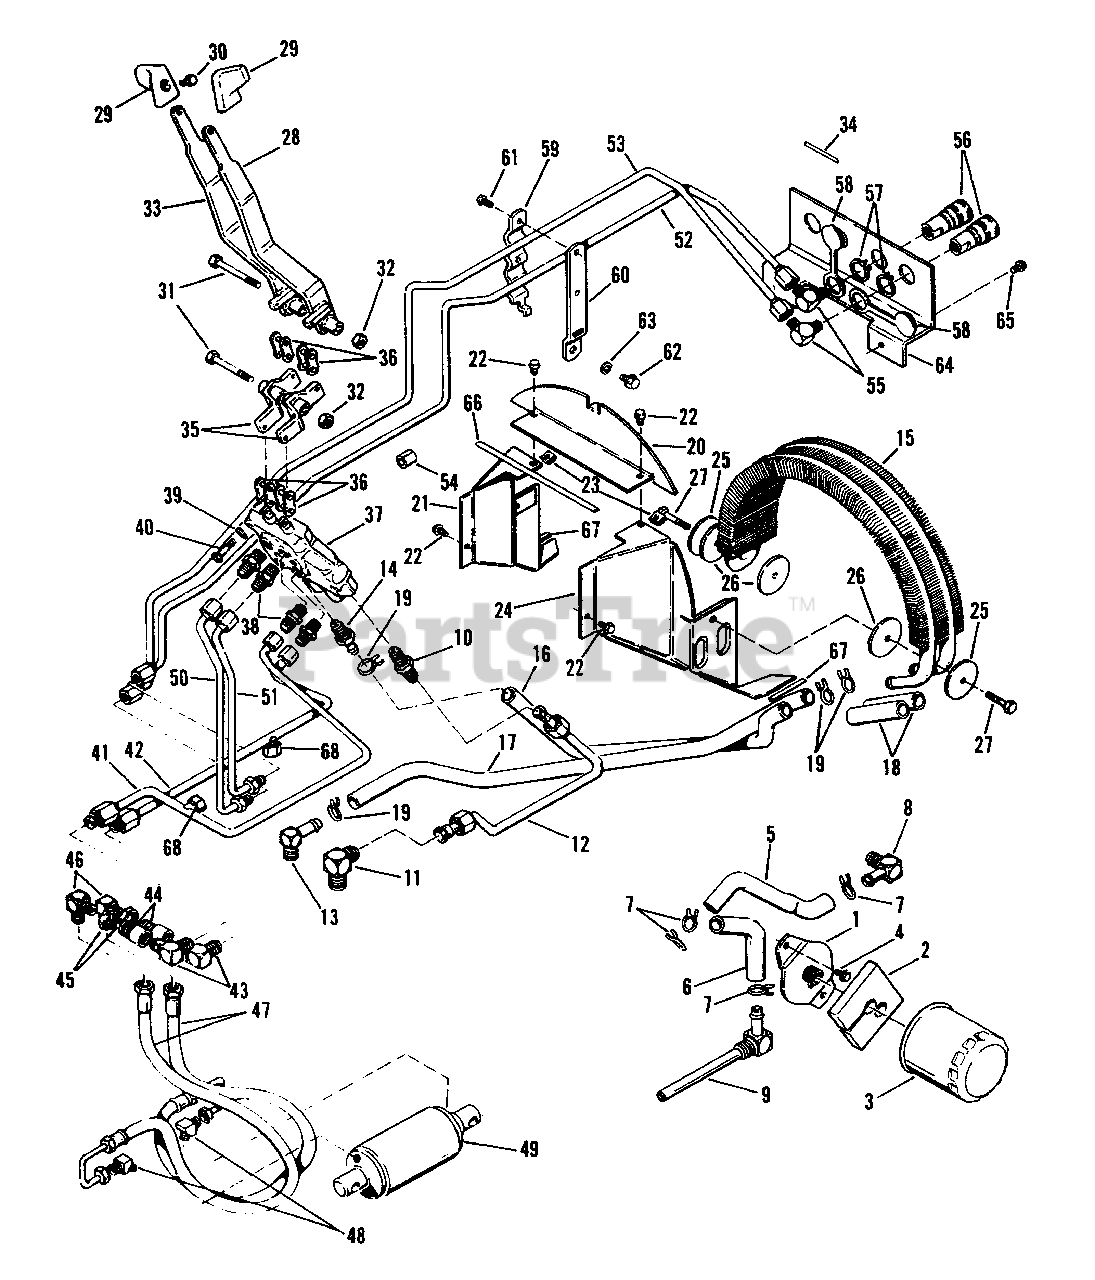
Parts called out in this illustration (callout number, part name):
1	Filter Plate Assembly
3	Oil Filter
4	Hex Capscrew, 5/16"-18 x 1/2" lg.
5	Hydraulic Hose
6	Hydraulic Hose
7	Hose Clamp
8	Elbow Assembly
10	Male Connector
12	Tube Assembly
14	Hose Connector
15	Oil Cooler
16	Hydraulic Hose
17	Hydraulic Hose
18	Hydraulic Hose
19	Hose Clamp
20	Upper Shroud (Rear)
21	Shroud Assembly, Left Hand
22	Thread Forming Screw, 1/4"-20 x 3/8" lg.
23	Speed Nut
24	Shroud Assembly, Right Hand
27	Thread Forming Screw, 1/4"-20 x 1-1/2" lg.
28	Lever Assembly
30	Thread Forming Screw, 1/4"-20 x 3/4" lg.
31	Hex Capscrew, 3/8"-16 x 2-3/4" lg.
32	Hex Jam Nut, 3/8"-16
33	Level Assy. (Mfg. Nos. 953 & 954)
34	Film "Power lift" (Mfg. Nos. 953 & 954)
35	Bellcrank Assembly
36	Connector Link
37	Hydraulic Valve (Mfg. No. 920)
37	Hydraulic Valve (Mfg. Nos. 953 & 954)
38	Male Connector
39	Lockwasher, 1/4"
40	Hex Capscrew, 1/4"-20 x 1-3/4" lg.
41	Tube Assembly
42	Tube Assembly
50	Tube Assy. (Mfg. Nos. 953 & 954)
51	Tube Assy. (Mfg. Nos. 953 & 954)
52	Tube Assy. (Mfg. Nos. 953 & 954)
53	Tube Assy. (Mfg. Nos. 953 & 954)
54	Spacer (Mfg. Nos. 953 & 954)
55	Elbow (Mfg. Nos. 953 & 954)
56	Body Assy. (Mfg. Nos. 953 & 954)
57	Retaining Ring (Mfg. Nos. 953 & 954)
58	Plastic Plug (Mfg. Nos. 953 & 954)
59	Clamp (Mfg. Nos. 953 & 954)
60	Bracket (Mfg. Nos. 953 & 954)
61	Taptite Screw, 1/4"-20 x 5/8" lg. (Mfg. Nos. 953 & 954)
62	Hex Capscrew, 3/8"-16 x 5/8" lg. (Mfg. Nos. 953 & 954)
63	Lockwasher, 3/8" (Mfg. Nos. 953 & 954)
64	Mtg. Plate (Mfg. Nos. 953 & 954)
65	Washer Hd. Screw, 1/4"-20 x 1/2" lg. (Mfg. Nos. 953 & 954)
